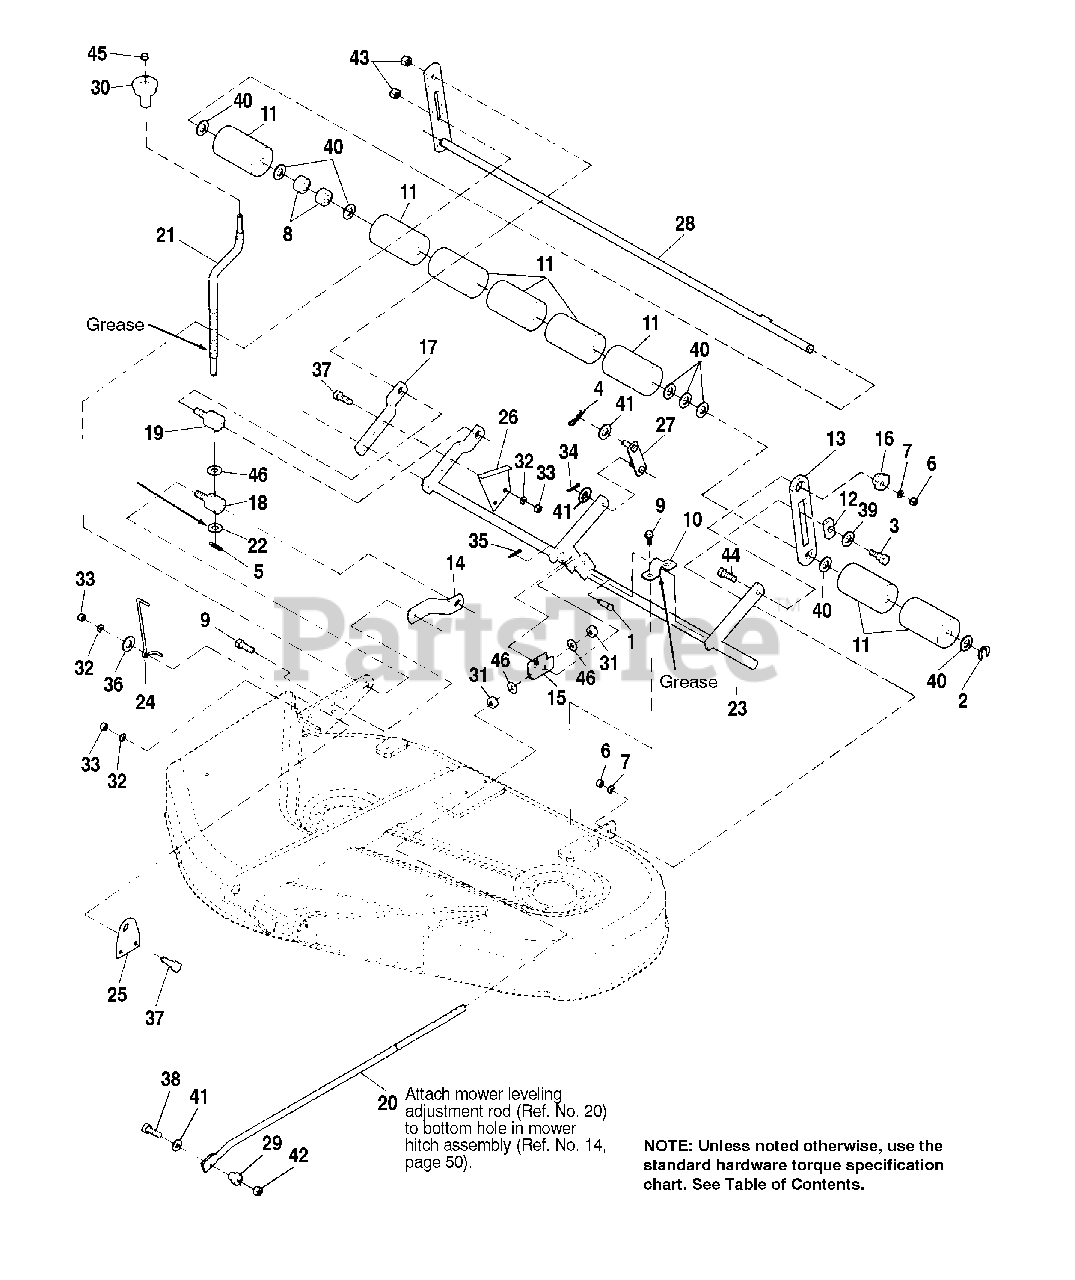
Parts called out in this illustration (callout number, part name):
1	PIN, Clevis
2	RING, Retaining
3	BOLT, Shoulder, 3/8-16 X 1.34
4	CLIP, Pin, Safety
5	PIN, Roll, 1"
6	NUT, Hex Hd., 3/8-16
7	LOCKWASHER, 3/8
8	SPACER, .66 ID
9	SCREW, Hex, Taptite, 5/16 x 3/4
10	STRAP, Mower Arm Assy.
13	BAR, Roller
14	STRAP, Trunnion Retainer
16	NUT, Hex Adjusting, .99 DIA .687
17	ARM, Rear, Mower, RH
19	TRUNNION, Threaded
20	ROD, Adjustment
21	CRANK, Cutting Height
22	WASHER, Detent
23	ARM ASSY., Mower
24	INDICATOR, Cutting Height
25	PLATE, Support
26	BRACKET, Cutting Height
27	LINK ASSY., Lift
28	SHAFT ASSY., Roller
31	NUT, Hex, Jam, 1/2-13
32	LOCKWASHER, 5/16
33	NUT, Hex, 5/16-18
35	COTTER PIN
36	WASHER, Flat, 5/16
37	CAPSCREW, Hex Hd., 5/16-18 x 1-1/4
38	CAPSCREW, Hex Head, 3/8-16 x 1-3/4
39	WASHER, Plain, 1/2
40	WASHER, 5/8
41	WASHER, Plain, 13/32
42	NUT, Hex, Whizlock, 3/8-16
43	NUT, Hex, Flange, Lock, 1/2-13
44	CARRIAGE BOLT, 3/8-16 x 1-1/2
45	PAL NUT
46	WASHER, 33/64
